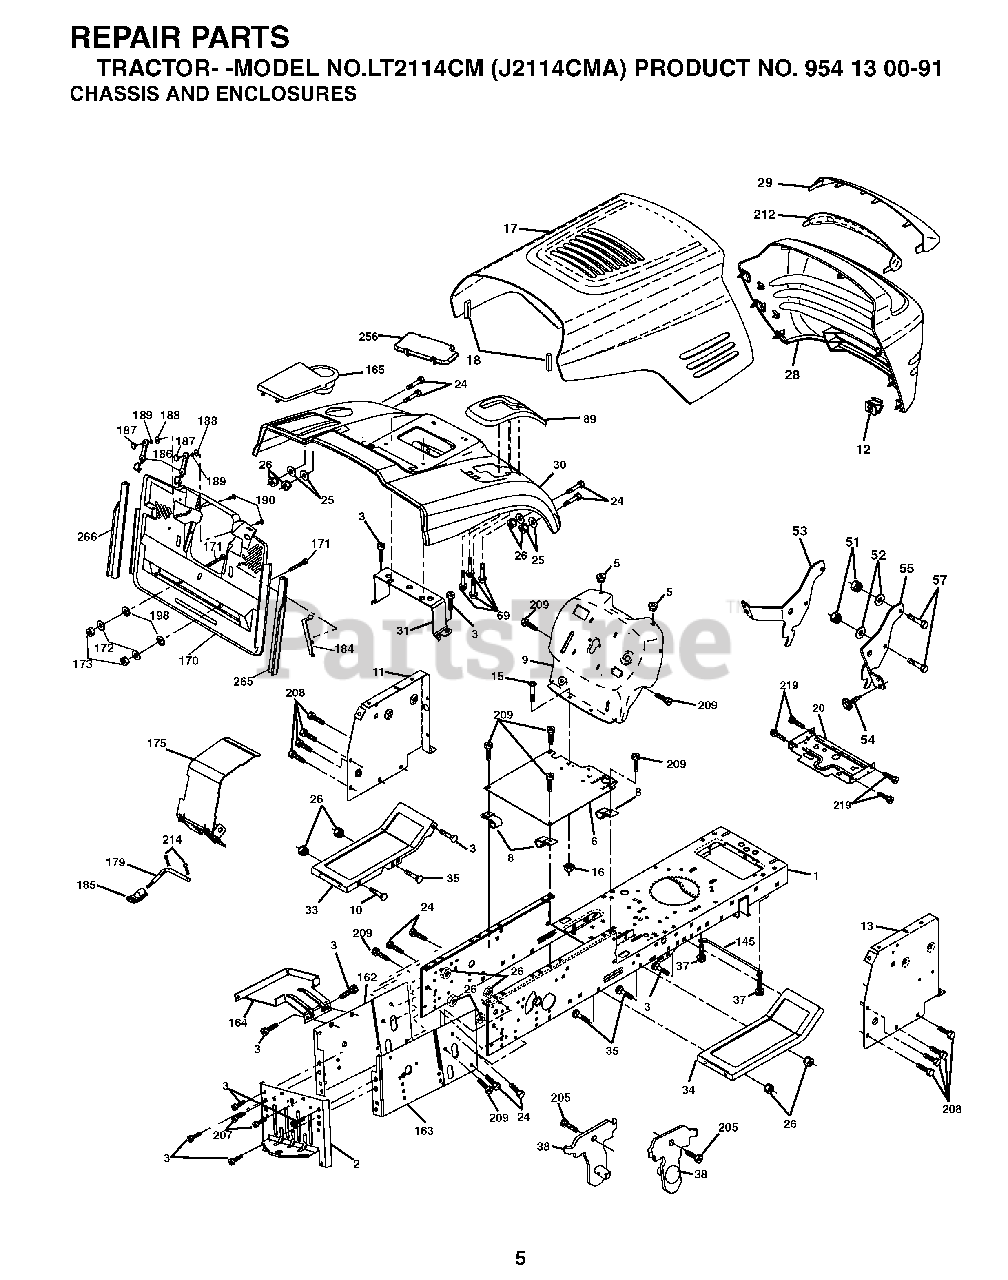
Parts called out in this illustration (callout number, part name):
1	CHASSIS
3	SCREW 3/8-16X3/4
5	BUMPER.RUBBER.HOOD
8	CLIP,INSULATOR
10	BOLT D
11	PANEL.DASH.LH.LTX
13	PANEL ASM, DASH RH
16	NUT
18	BUMPER.HOOD.LARGE.1.75"
20	PLATE MTG.BATTERY/FUEL TANK
24	BOLT
25	WASHER
26	NUT
31	BRACKET SUPPORT FENDER
35	BOLT
37	SCREW LT
51	LOCKNUT
52	WASHER
57	BOLT
69	SCREW.HI-LO.CONSOLE
145	ROD PIVOT CHASSIS/HOOD
164	SUPPORT
171	BOLT
172	WASHER
186	LATCH ASSY
187	WELDNUT
189	LOCKWASHER
190	SCREW
205	SCREW LT
207	SCREW 5/16-18X1/2"
208	SCREW 3/8-16X1/2
209	SCREW, 3/8-16X3/4
214	RETAINER M
219	SCREW
